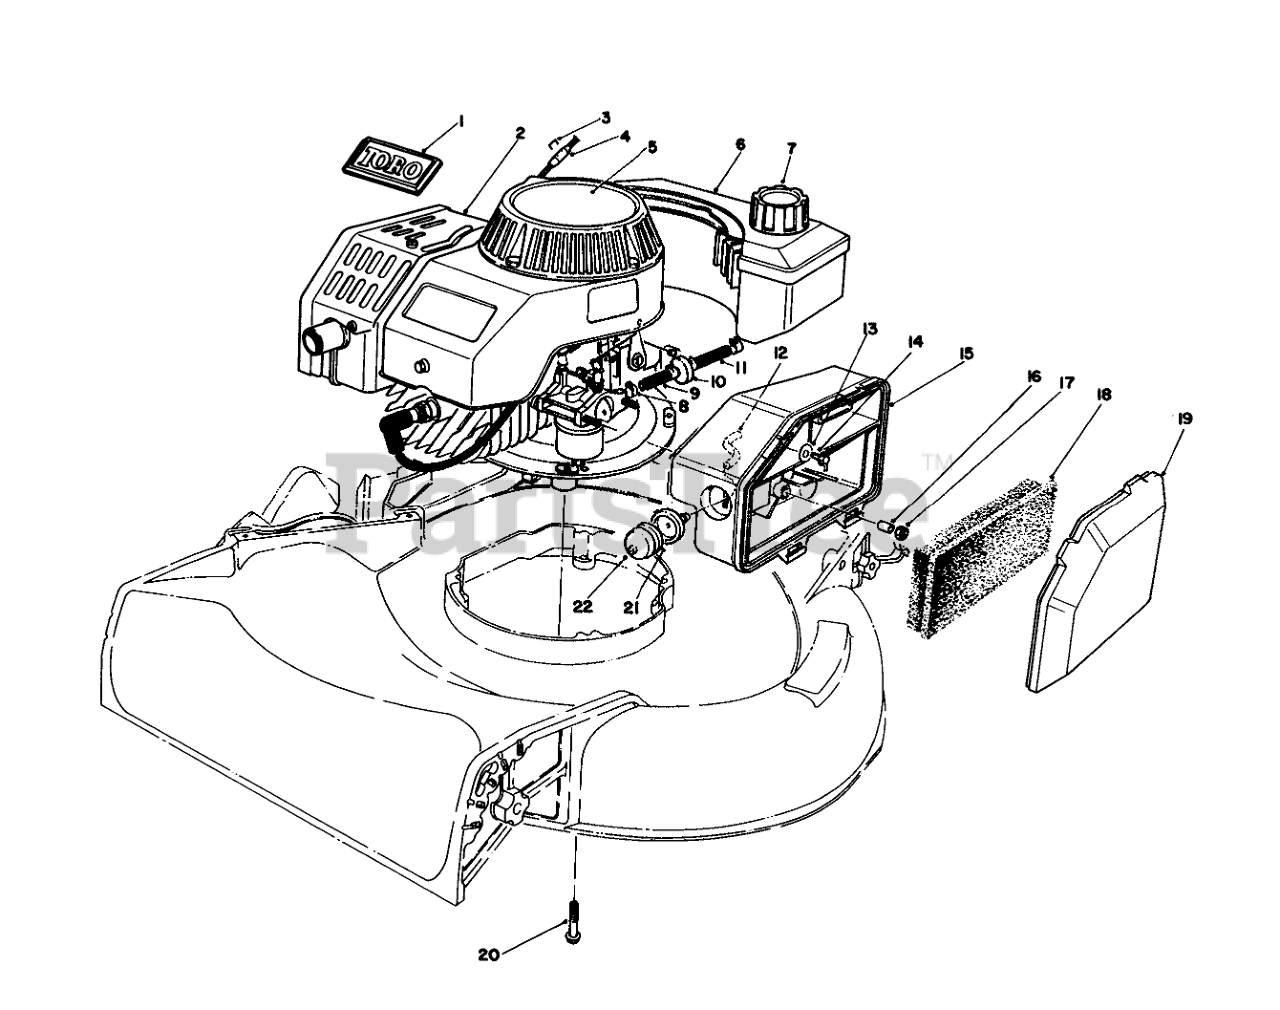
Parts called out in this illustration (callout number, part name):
1	TORO LOGO PLT
2	Engine
3	Staple
4	STOP-ROPE
5	DECAL- 2 CYC RECOIL
6	FUEL TANK ASM
7	GAS CAP ASM
8	CLAMP-FUEL LINE
9	HOSE-FUEL
10	FILTER-FUEL
11	HOSE-FUEL
12	HOSE-PRIMER
13	WASHER-FLAT
14	SCREW-HH
15	BODY-AIR CLEANER
16	SPACER
18	ELEMENT-AIR CLEANER
19	COVER-AIR CLEANER
20	SCREW-HHF, WHIZ
21	BODY-PRIMER
22	Bulb Primer
23	Fuel Filter Kit (Incl. Ref. #8-11)
